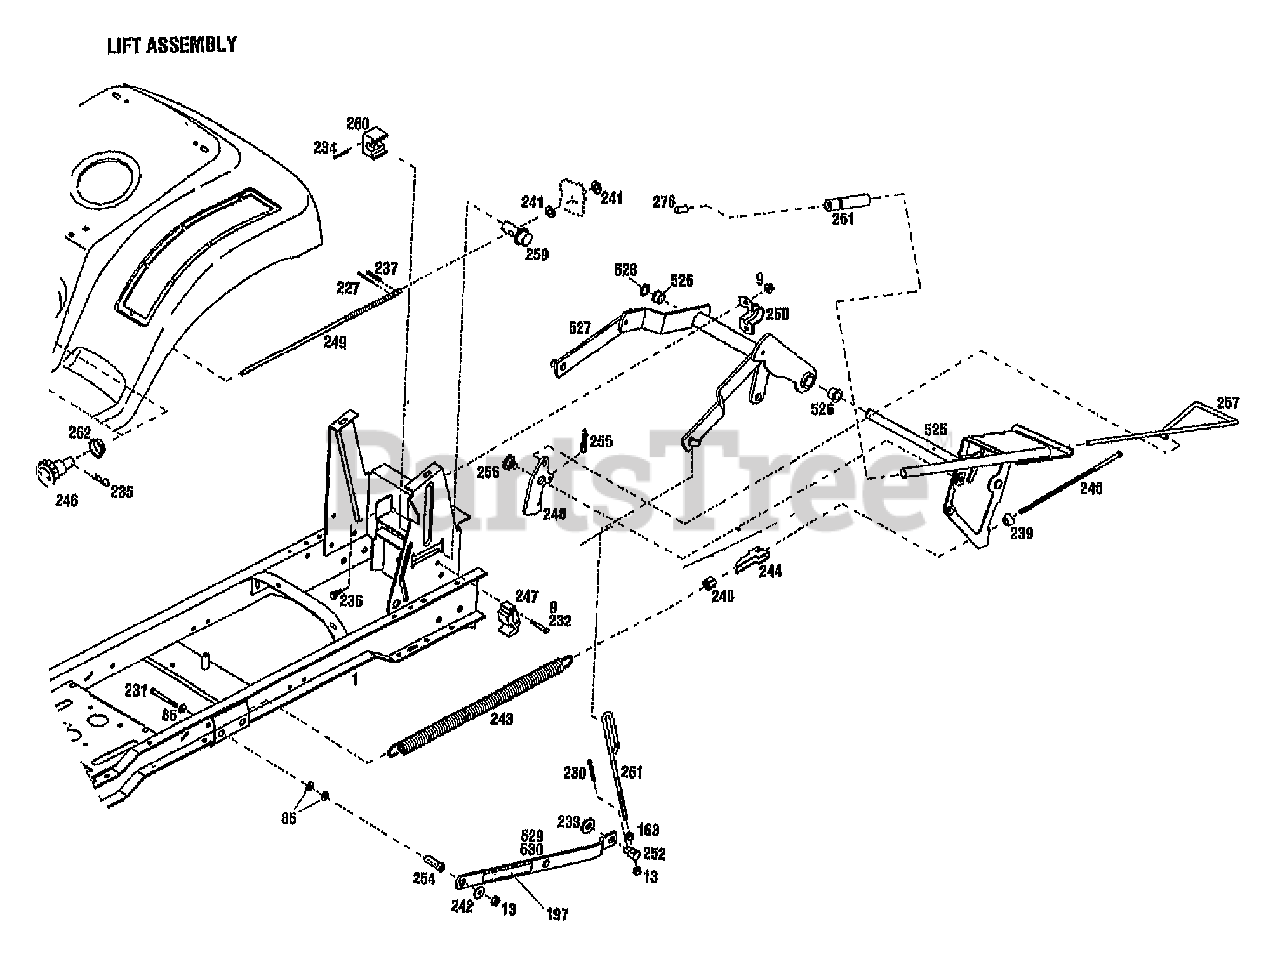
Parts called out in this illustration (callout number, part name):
1	ASSM-FRAME LTX
9	NUT-HFLK 5/16-18 ZP
13	NUT-LOCK 3/8-16
85	WASHER-FLAT 3/8 SAE
163	NUT-HEX 3/8-16 ZP
197	DECAL-WARNING
227	PIN-COTTER .125 X .75 ZP
230	PIN-COTTER .120X1.25 ZP
231	SCR-HH 3/8-16X3.0 G5 ZP
232	SCR-HH 5/16-18X1.5 G5 ZP
233	WASHER-1.305X.649X.098 ZP
234	PIN-DRIVE
235	PIN-HITCH
236	SCR-HFLK 5/16-18X.75 ZP
237	PIN-ROLL .156X1.0
239	BEARING-SPHERICAL
240	NUT-SPECIAL 5/16-18
242	WASHER-1.5X.375X.18 ZP
243	SPRING-LIFT ASSIST
244	BRKT-LIFT ASSIST
245	SCR-LIFT ASSIST
246	KNOB-HEIGHT ADJUST
247	BLOCK-DETENT
249	KIT-SVC SCR HGT ADJ
250	CLAMP-LIFT
252	SWIVEL-LIFT REAR
254	SPACER
255	SPRING-EXTENSION
256	SCR-SHOULDER
259	BLOCK-HEIGHT ADJUST
260	COLLAR-HEIGHT ADJUST
261	GRIP-LIFT
262	GROMMET-SNAP BUSHING
276	BUTTON-LIFT
525	HANDLE-LIFT
528	RING-RETAINING EXT .694 ID
529	LINK-LIFT W/DECAL
530	LINK-LIFT W/DECAL
